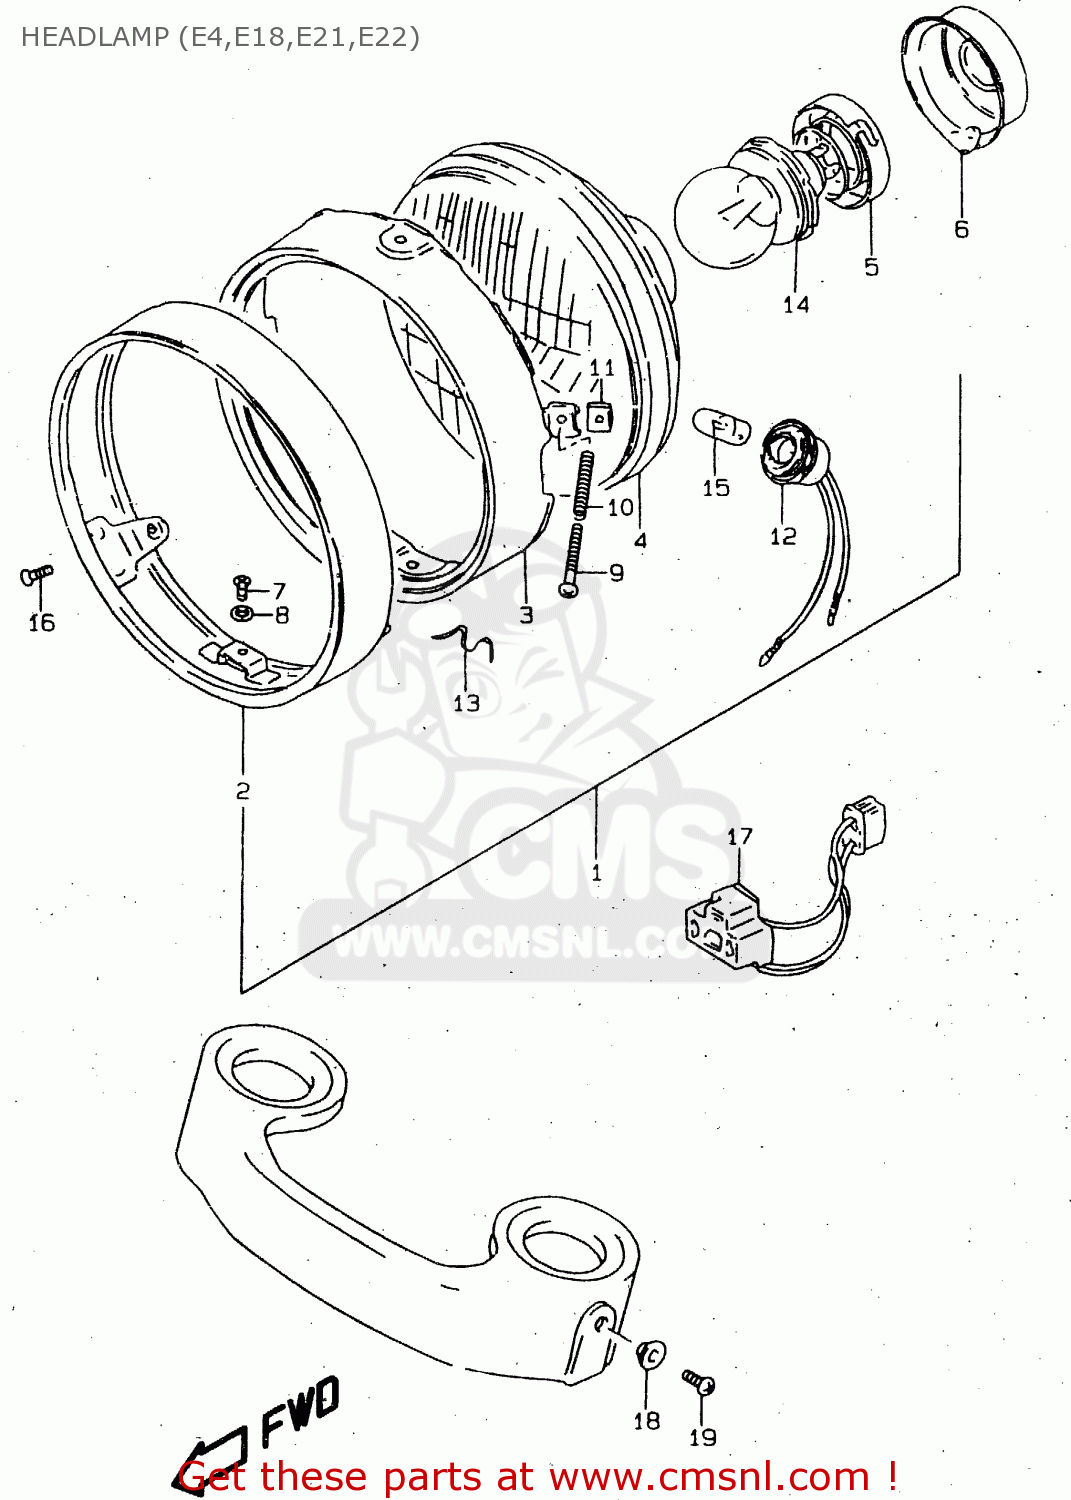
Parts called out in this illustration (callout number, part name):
1	HEADLAMP ASSY
2	RIM
3	RETAINER
4	LAMP UNIT
5	SETTER,BULB
6	COVER,HEADLAMP BULB
7	SCREW
8	WASHER,LOCK
9	SCREW
10	SPRING
11	NUT
12	SOCKET
13	SPRING
14	BULB(12V45/40W)
15	BULB(12V4W)
16	SCREW
17	LEAD WIRE,HEADLAMP
18	WASHER
19	SCREW
